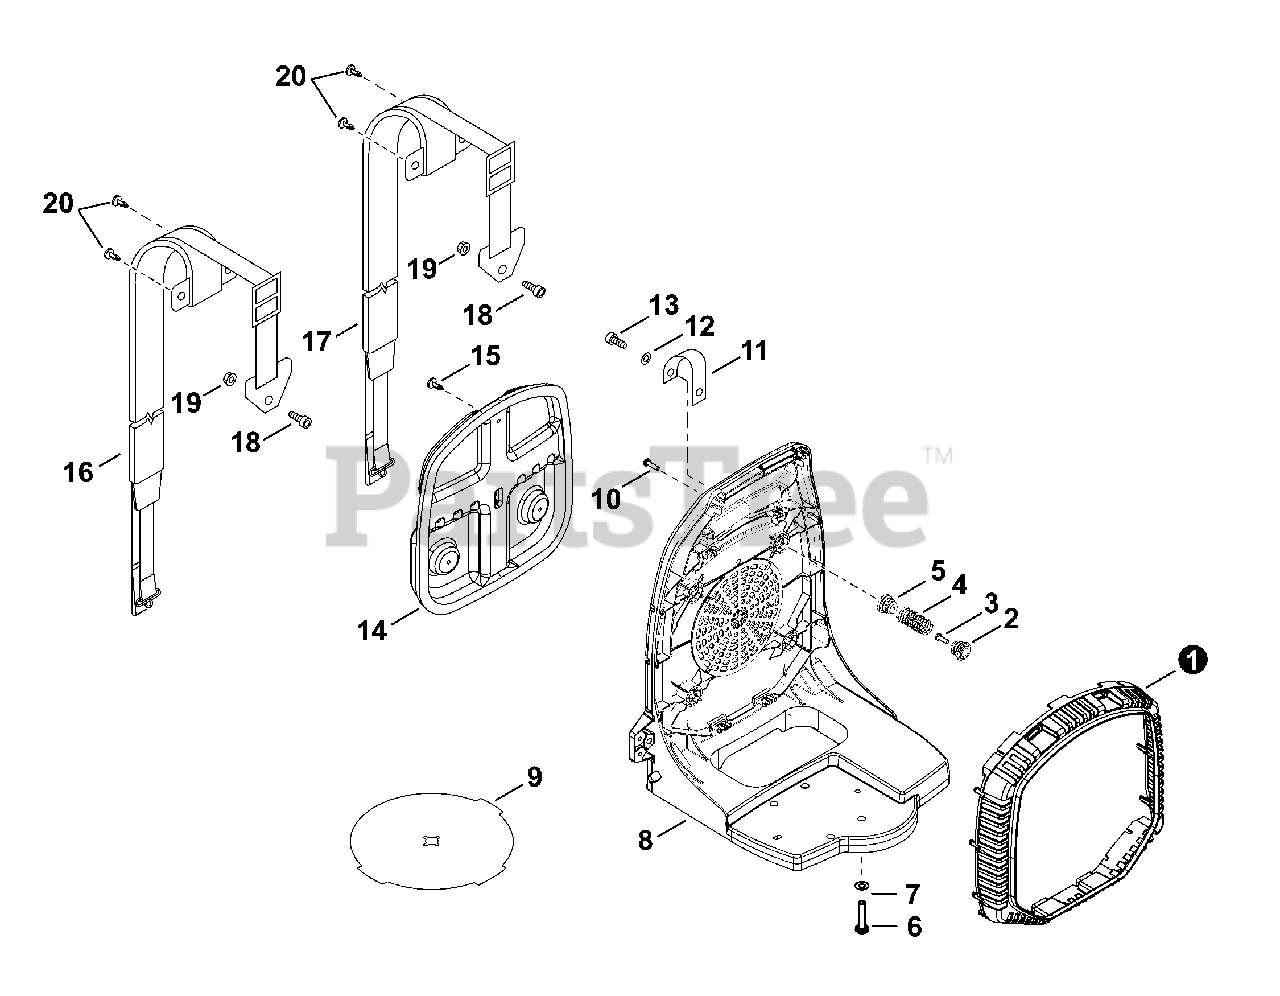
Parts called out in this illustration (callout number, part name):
1	GUARD, DEBRIS
2	HOLDER, SPRING
3	BOLT, TORX 5×16
4	SPRING, COMPRESSION
5	HOLDER, SPRING
6	SCREW 5×25
7	WASHER 5.5×16×2T
8	FRAME, BACKPACK
9	INSERT, COLD WEATHER
10	BOLT, TORX 5×20
11	STRAP, SAFETY 1.2×100
12	WASHER 5.5×16×2T
13	BOLT, TORX 5×20
14	CUSHION, BACKPACK
16	HARNESS ASSY, LEFT
17	HARNESS ASSY, RIGHT
18	BOLT, TORX 5×30
19	NUT, LOCK M5
